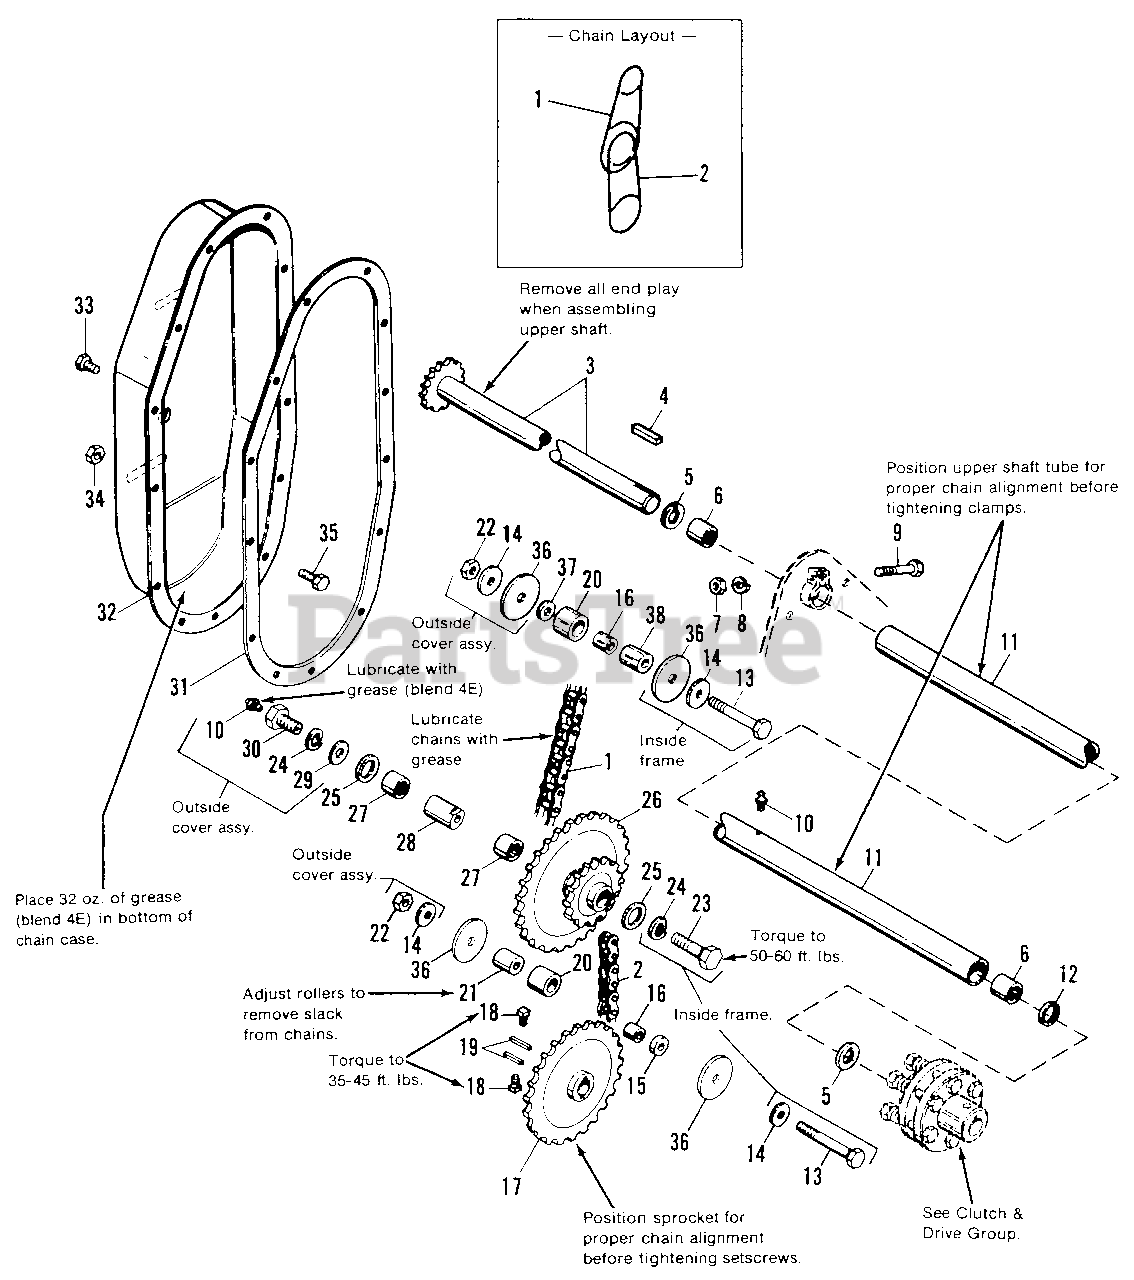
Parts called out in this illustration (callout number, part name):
1	CHAIN, Roller
2	CHAIN, Roller
3	SHAFT & SPROCKET ASSY.
4	KEY
6	BEARING, Needle
7	NUT, Hex, Full, 5/16-18
8	LOCKWASHER, 5/16
9	CAPSCREW, Hex, 5/16-18 x 1-1/2
10	FITTING, Grease
11	HOUSING ASSY.
12	SEAL, Shaft Assy.
13	CAPSCREW, Hex Hd., 3/8-16 x 4
14	WASHER, Special, 13/32 x 1-1/2
16	SPACER, Chain Roller
17	SPROCKET ASSY.
18	SETSCREW, Sq. Hd., 3/8-16 x 3/4
20	ROLLER, Chain
22	LOCKNUT, Hex, 3/8-16
23	CAPSCREW, Hex Hd., 1/2-20 x 1
24	LOCKWASHER, 1/2
26	SPROCKET ASSY.
29	WASHER, 1/2
30	BOLT, Side R.H.
32	COVER ASSY.
33	SCREW, Hex Taptite, 5/16-18 x 1/2
34	LOCKNUT, Hex, 5/16-18
35	CAPSCREW, Hex Hd., 5/16-18 x 5/8
37	WASHER, Special, 3/8 x 1
